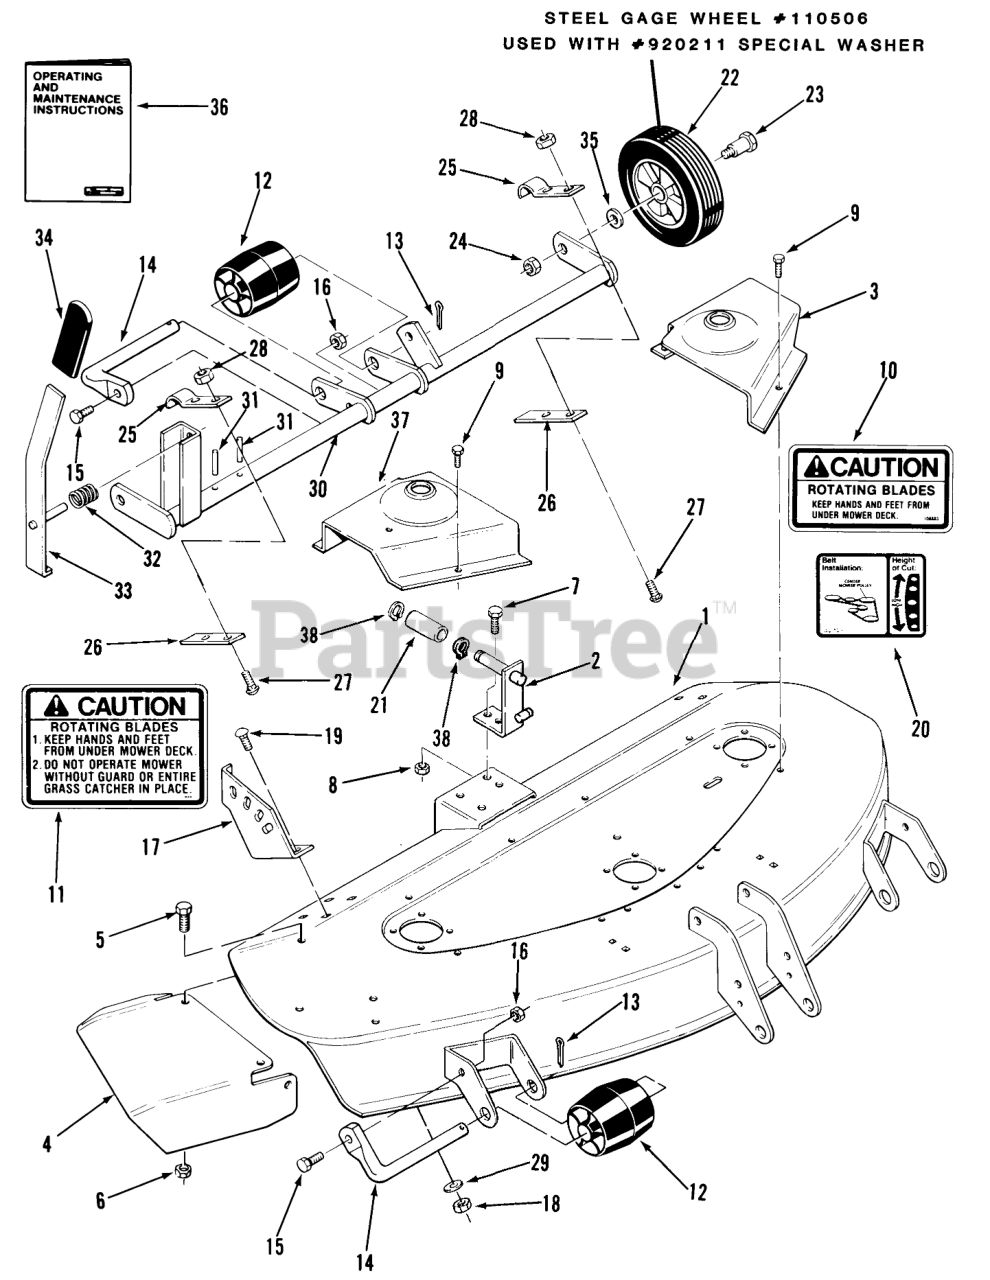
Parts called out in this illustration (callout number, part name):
1	Deck
2	Guide Bracket
3	COVER-BELT LH R
4	Chute Extension
5	Bolt
6	Nut
7	BOLT
8	Nut
9	SCREW -4
10	Caution Decal
11	DECAL
12	Roller
13	Cotter Pin
14	Roller Shaft
15	H H C S
16	Nut
17	Quadrant
18	Nut
19	Bolt-Carriage
20	DECAL-HEIGHT BELT
21	SPACER
22	Wheel 6 x 1.75
23	BOLT-SHOULDER
24	Nut
25	Machine Bolt
26	Bar
27	Bolt
28	NUT
29	Washer
30	Gage Wheel Support
31	PIN-SPIROL
32	SPRING-COMPRESSION
33	LEVER ASSY R
35	WASHER
36	Operating & Maintenance Instructions
37	COVER-BELT RH R
38	Snap Ring
